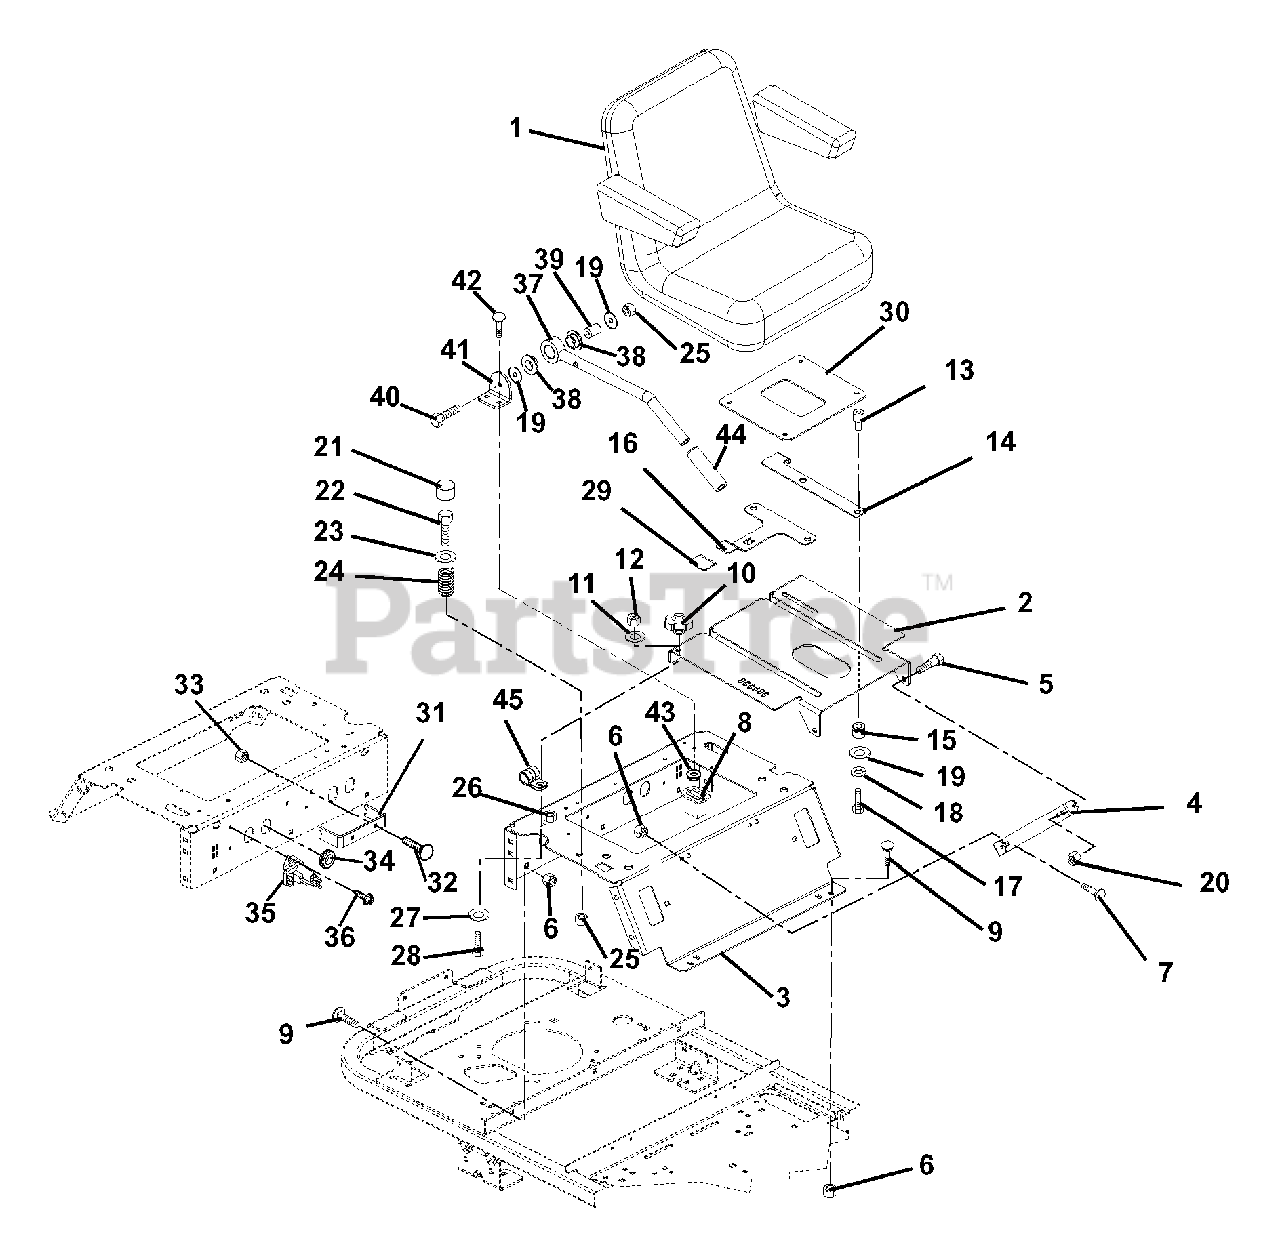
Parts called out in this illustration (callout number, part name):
1	SEAT, HIGH BACK 2805 SERIES
2	SEAT PLATE
3	SEAT SUPPORT
4	BRACKET, SEAT PLATE
5	BOLT-SHLDR .375-16X.150
6	@NUT-LK-NYL-FLG .38-16 YWZC
7	@BLT-RDHDSQNK .38-16X1.00 G5YZ
8	HOURMETER-QUARTZ 80VDCMAX
9	@BLT-RDHDSQNK .38-16X1.00 G5YZ
10	KNOB-CLAMPING, .312-18 NYLOC
11	WSHR-FL-STL .328X1.0X.094 YWZC
12	@NUT-LK-NYL .312-18 YWZC
13	SPACER, SEAT TOP
14	SEAT STOP
15	SPACER, SEAT BOTTOM
16	LEVER, SEAT ADJUSTMENT
17	@BLT-HEX .31-18X2.25 GR5 YWZC
18	@WSHR-LK .31X.078 REG YWZC
19	WSHR-FL-STL .347X1.254X.048YWZ
20	@NUT-LK-TOP-FLG .38-16 YWZC
21	HUB CAP
22	@BLT-HEX .31-18X1.00 GR5 YWZC
23	WSHR-FL-STL .328X1.0X.094 YWZC
24	SG. COMP 2.9L X 2.02OD 200LB
25	@NUT-LK-NYL-FLG .31-18 YWZC
26	@NUT-SPNLK-FLG .312-18 YWZC
27	WSHR-FL-STL .505X1.00X.062YWZC
28	@BLT-RDHDSQNK .31-18X3.50 G5YZ
30	SEAT SUPPORT PLATE
31	BRAKE ROD SUPPORT
32	@BLT-RDHDSQNK .31-18X1.00 G5YZ
33	@NUT-LK-NYL-FLG .31-18 YWZC
34	GROMMET 1.0ID X 1.38 OD
35	SOLENOID
36	@SCR-TAP .25-20X.37 HWH YWZ TR
37	WMT, PARK BRAKE
38	BSHG-FLG .762X1.48X.44 NYL
39	SPACER .328 X .76 X 1.01
40	@BLT-HEX .31-18X1.75 GR5 YWZC
41	BRKT, BRAKE HANDLE PIVOT
42	@BLT-RDHDSQNK .25-20X.75 G5YZ
43	@NUT-LK-TOP-FLG .25-20 YWZC
45	CLAMP, CUSHIONED STEEL
